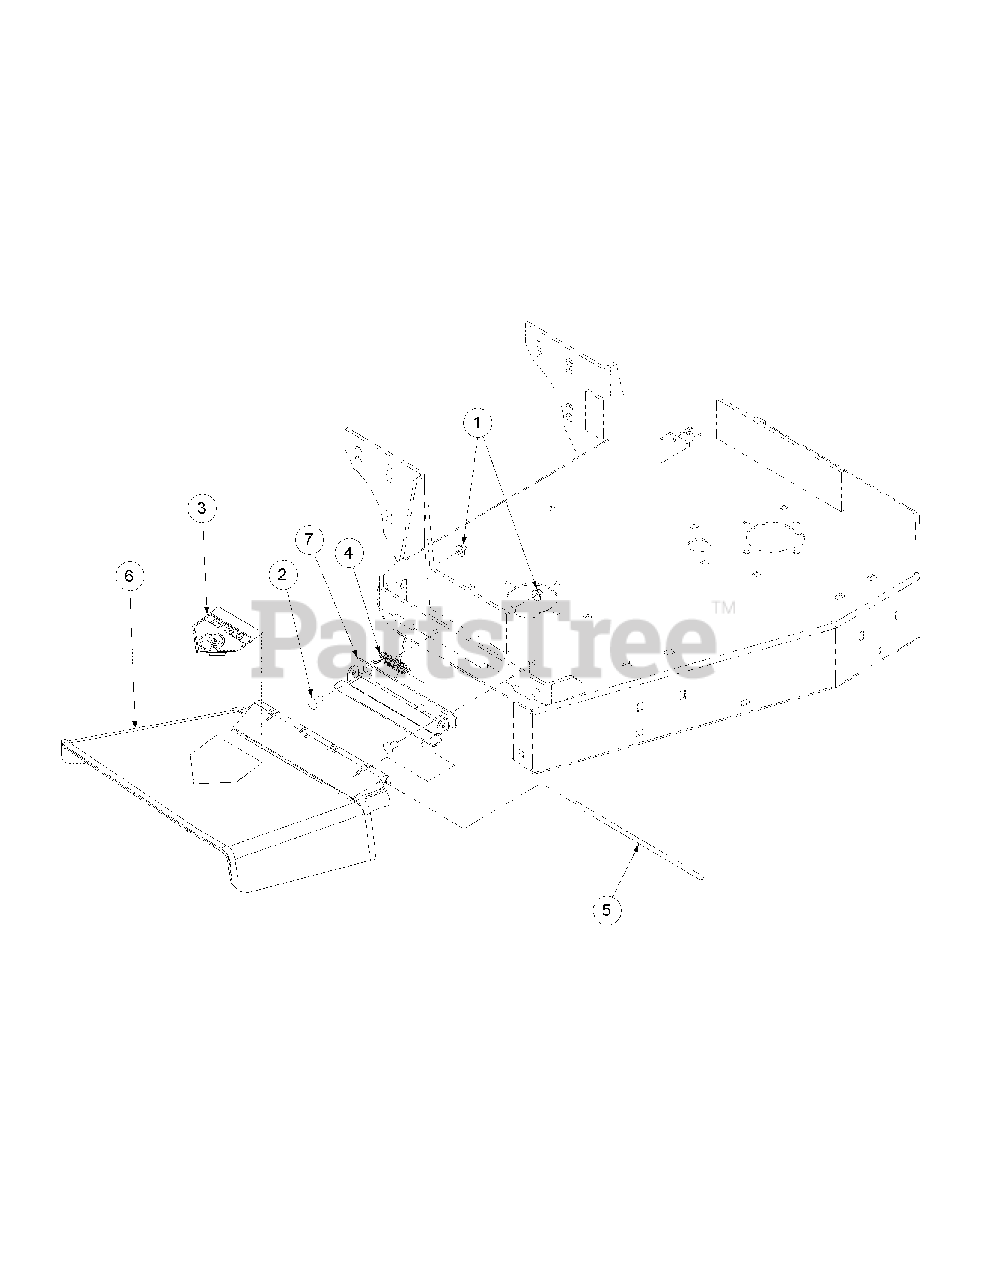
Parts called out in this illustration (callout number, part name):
1	Hex Nut Flange Lock, 3/8-16
2	Carriage Bolt, 3/8-16 x 1.00 LG.
3	Decal, Danger Hands and Feet
4	Torsion Spring
5	Chute Deflector Rod
6	Deflector Chute
7	Deflector Chute Bracket
